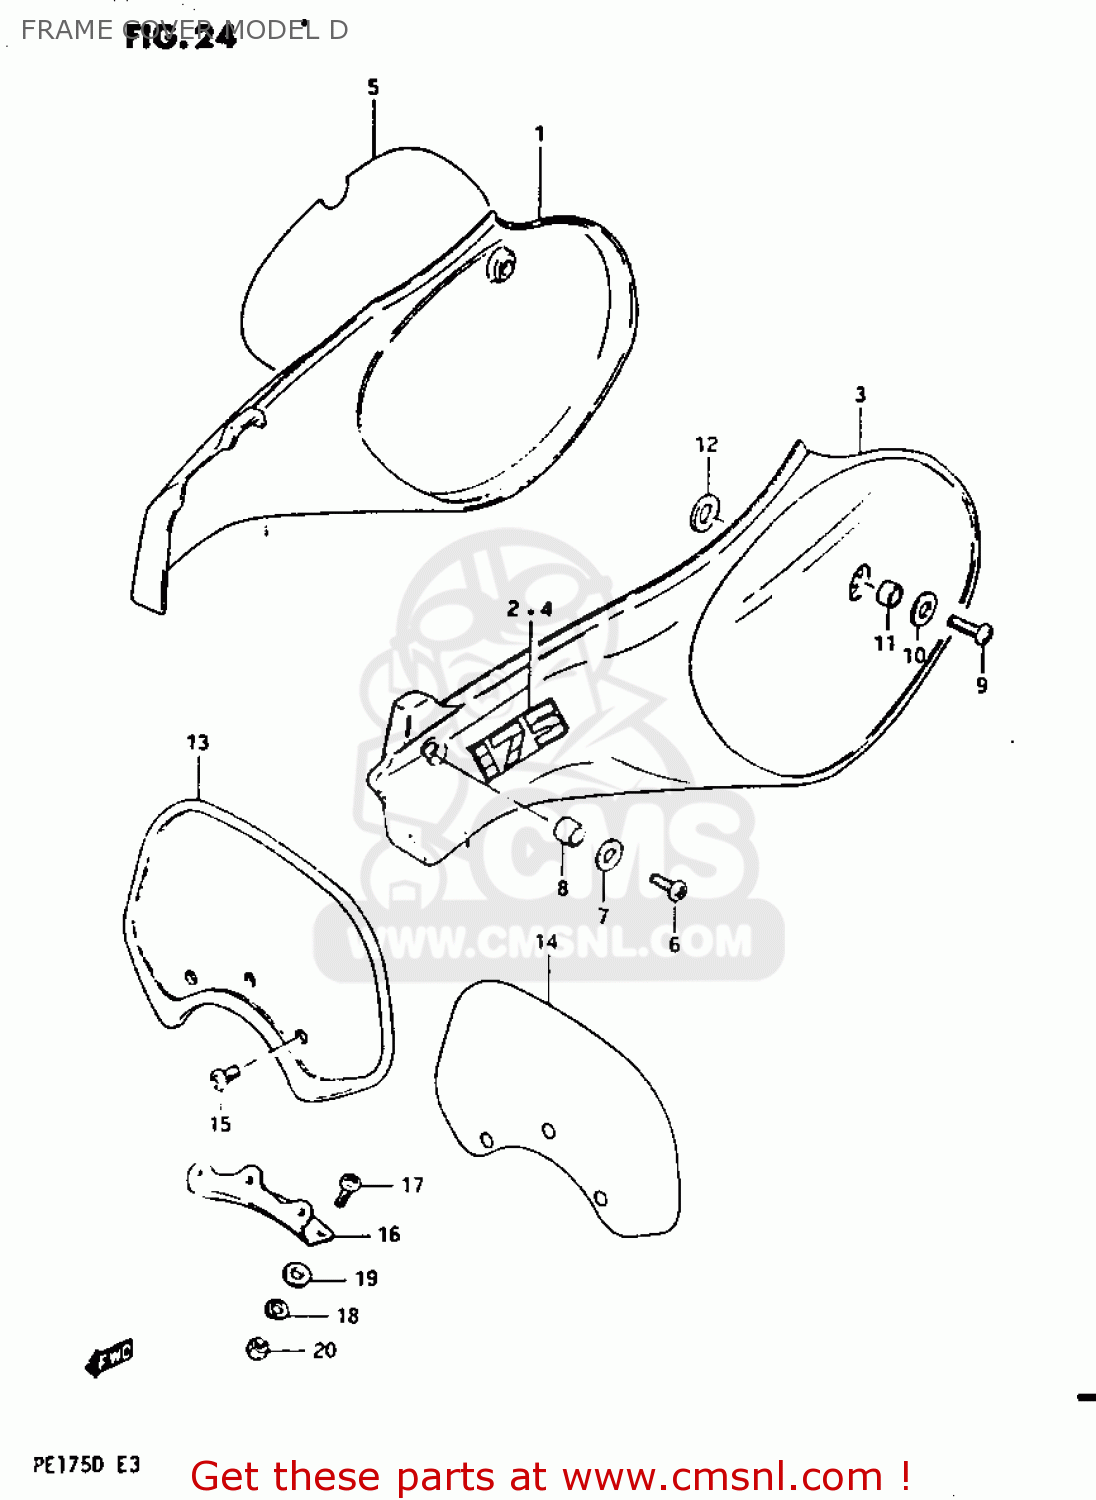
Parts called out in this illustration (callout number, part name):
1	COVER,FRAME,RIGHT
2	EMBLEM,FRAME COVER,RIGHT
3	COVER,FRAME,LEFT
4	EMBLEM,FRAME COVER,LEFT
5	EMBLEM,NBR PLATE
6	SCREW
7	WASHER
8	SPACER (6.1X8X12)
9	SCREW
10	WASHER
11	SPACER
12	GASKET
13	PLATE,FRONT NUMBER
14	EMBLEM,FRONT NUMBER PLATE
15	SCREW
16	BRACKET FR NUM PLATE
17	SCREW
18	LOCK WASHER
19	WASHER
20	NUT
